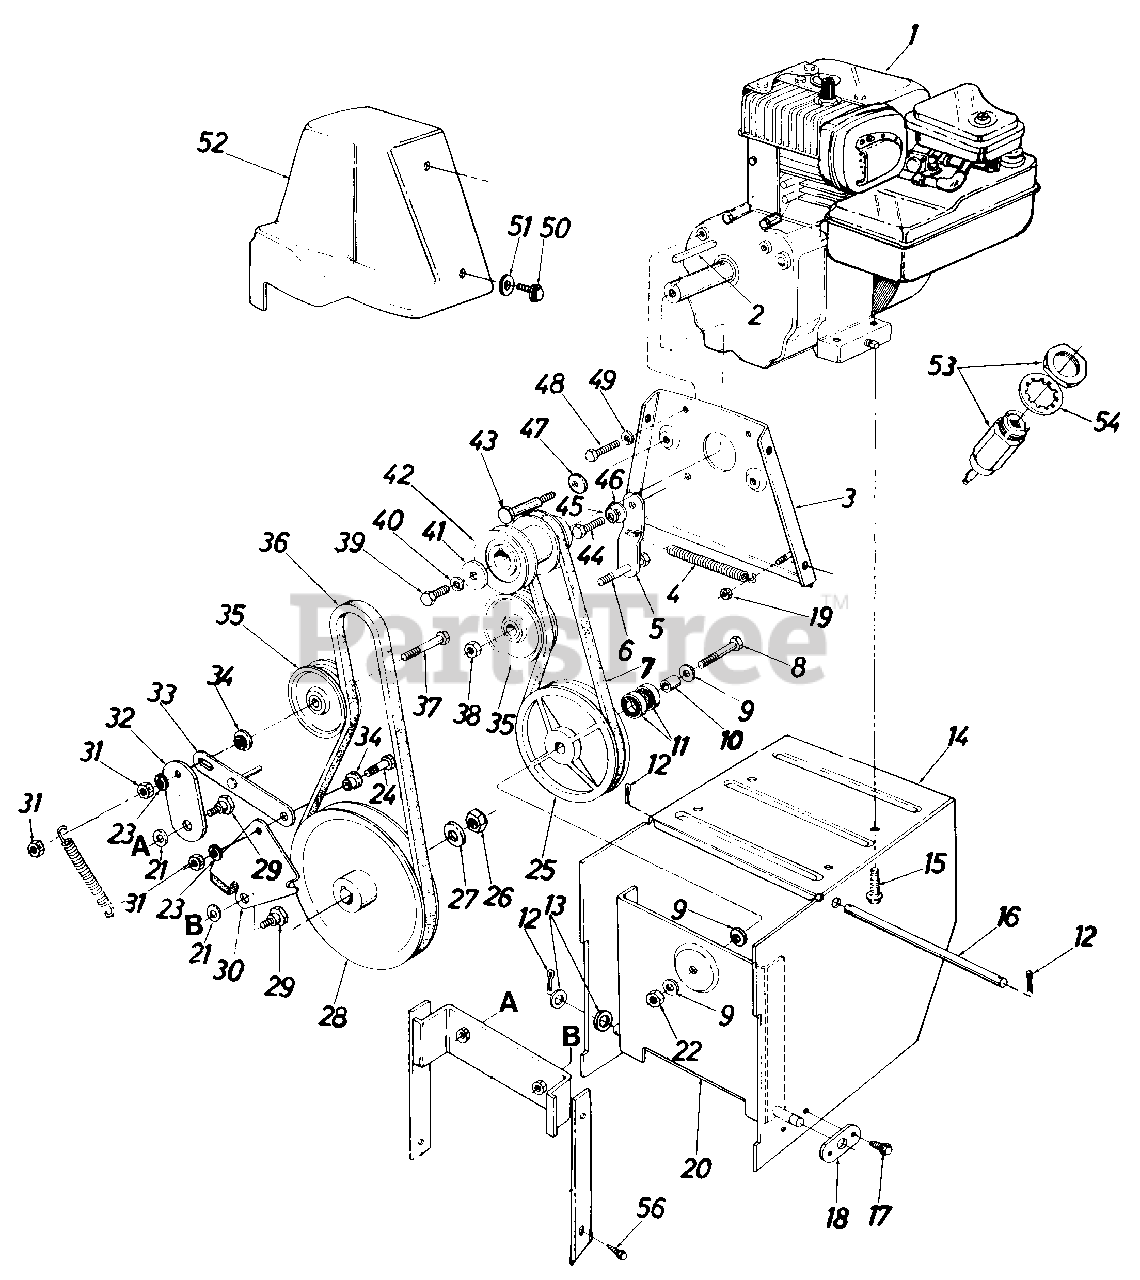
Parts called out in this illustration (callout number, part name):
1	Engine
2	Sq. Key 3/16" x 1.50" Lg.
3	Engine Plate Ass'y.
4	Extension Spring .50" O.D. x 3.97" Lg.
5	Drive Clutch Idler Brkt.
6	Hex Bolt 3/8-24 x 1.25" Lg.*
7	"V"-Belt 3/8" x 29.0" Lg.
8	Hex Bolt 3/8-24 x 1.50" Lg.*
9	Bell-Wash. .40" I.D. x .88" O.D. x .06
10	Spacer.38" I.D. x .62" O.D. x.75" Lg.
11	Ball Brg 62" I.D. x 1.38" O.D. x .44
12	Cotter Pin 3/32" Dia. x .75" Lg.**
13	Fl-Wash. .53" I.D. x 1.00" O.D. x .125
14	Frame Ass'y.
15	Hex Wash. Hd. Self-Tap Scr. 3/8-16 x 1.25" Lg.
16	Shaft .50" Dia. x 9.50" Lg.
17	Hex Wash. Hd. Self-Tap Scr. 1/4-20 x .50" Lg.
18	Axle Bracket
19	Hex L-Nut 1/4-20 Thd.
20	Drive Pulley Support Brkt. Ass'y.
21	Bell-Wash. .40" I.D. x 1.13" O.D.
22	Extension Spring .50" O.D. x 3.97" Lg.
23	L-Wash. 3/8" I.D.*
24	Hex Scr. 3/8-16 x 1.25" Lg.
25	6.00" O.D. Drive Pulley Ass'y. (Incl. Ref. #11)
26	Hex Jam Cent. L-Nut 5/8-18 Thd.
27	Fl-Wash. .64" I.D. x .94" O.D. x .06
28	1/2" V-Pulley .625" I.D. x 7.50" O.D.
29	Shld. Bolt .625" Dia. x .170" Lg. (3/8-16)
30	Brake Bracket Ass'y.
31	Hex Ins. L-Nut 3/8-16 Thd.
32	Auger Clutch Idler Brkt.
33	Brake Linkage Ass'y.
34	Shld. Spacer.625" I.D.
35	Flat Idler 2.25" O.D.
36	"V"-Belt 3/8" x 38" Lg.
37	Hex Bolt 3/8-16 x 2.25" Lg.*
38	Hex Ins. Jam L-Nut 3/8-24 Thd.
39	Hex Bolt 3/8-24 x 1.50" Lg.
40	L-Wash 3/8" I.D.*
41	Fl-Wash .40" I.D. x 1.25" O.D
42	Double Groove Engine Pulley
43	Shld. Scr. .498" x 3.0" Lg.
44	Hex Bolt 5/16-24 x 1.00" Lg.*
45	L-Wash 5/16" I.D.*
46	Shld. Spacer .320" I.D.
47	Bell-Wash. .40" I.D. x .88" x .06
48	Hex Bolt 5/16-24 x .62" Lg.*
49	L-Wash. 5/16" I.D.*
50	Hex Wash. Hd. Self-Tap Scr. 1/4-20 x .50" Lg.
51	Fl-Wash. .28" I.D. x .75" O.D. x .06
52	Belt Cover
53	Ignition Switch
54	Int. L-Wash. 5/8" I.D.
56	Hex Wash. Hd. Self-Tap Scr. 3/8-16 x . 75 " Lg .
